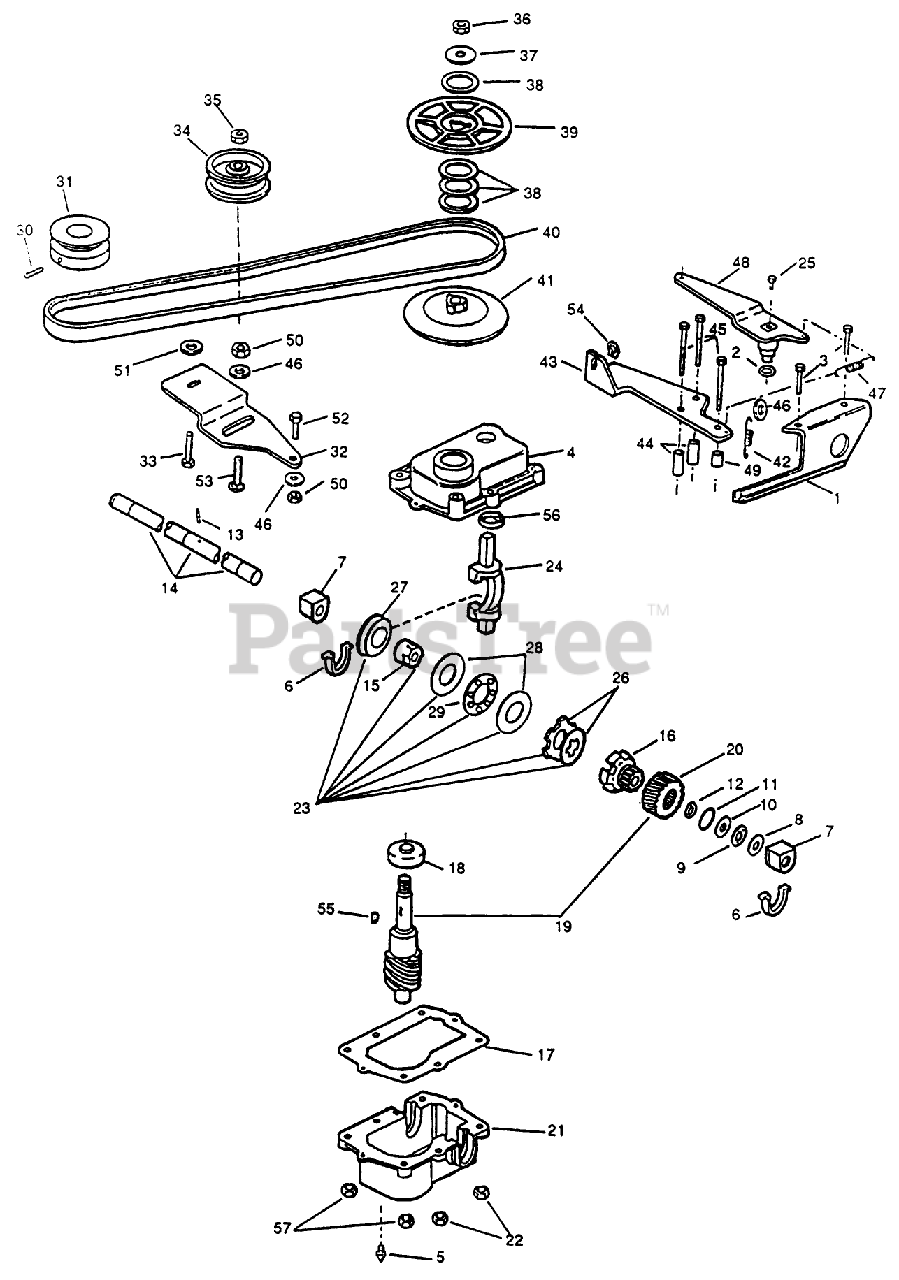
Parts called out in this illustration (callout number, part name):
2	O-RING
7	BEARING & SEAL AY (12)
8	THRUST WASHER
10	WASHER-THRUST
12	RET RING
13	PIN DRIVE LOCK
16	DRIVER BROCKWAY
17	GASKET HOOSIER
18	BEARING-BALL
20	WORM WHEEL
22	LOCKNUT E
24	FORK SHIFT
25	SCREW SEMS SM
26	Disc Plate Kit
27	Collar
30	SET SCREW F
31	PULLEY F
34	PULLEY IDLER NHI
35	NUT-JAM, LOCKING
36	LOCKNUT
37	WASHER
39	PULLEY UPPER PL
40	V-BELT F
41	PULLEY LOWER PL
42	SPRING EXTEN D&B
43	CONDUIT ANCHOR BRKT
46	WASHER S
47	SPRING
50	NUT-LOCK F
51	WASHER
54	RET. RING
55	KEY GALGER
56	GUIDE ELCO
57	LOCKNUT E
